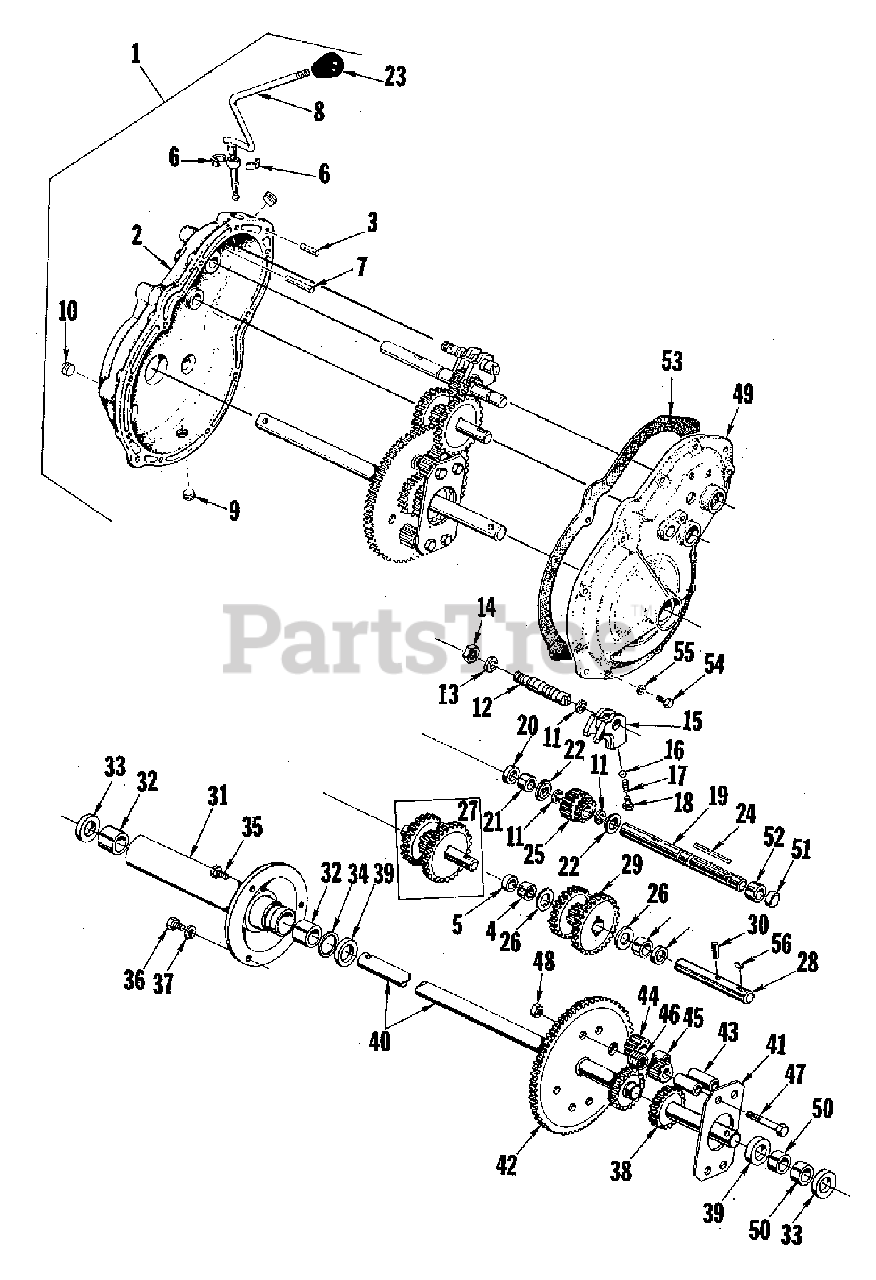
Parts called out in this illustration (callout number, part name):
1	GEAR CASE ASSEMBLY
5	PLUG, Expansion
6	BUSHING, Ball Half
8	SHIFT ROD ASSEMBLY
11	RETAINING RING
12	SHAFT, Shift
13	WASHER, Lock, 7/16
14	NUT, Hex Full, 7/16
18	SCREW, Hex, 5/16-18 x 5/16
19	SHAFT, Pulley
25	PINION ASSEMBLY
27	SHAFT & GEAR ASSEMBLY
28	SHAFT, Brake
29	GEAR CLUSTER ASSEMBLY
31	HOUSING, Axle
35	SCREW, Special
36	SCREW, Hex, 3/8-16 x 7/8
37	WASHER, Lock, 3/8
41	PLATE, Differential
42	DRIVE GEAR ASSEMBLY
47	SCREW, Hex, 3/8-16 x 2-1/2
48	NUT, Hex Full Lock, 3/8-16
49	GEAR COVER ASSEMBLY
51	PLUG, Expansion
54	SCREW, Hex, 5/16-18 x 1-1/4
55	WASHER, 5/16
